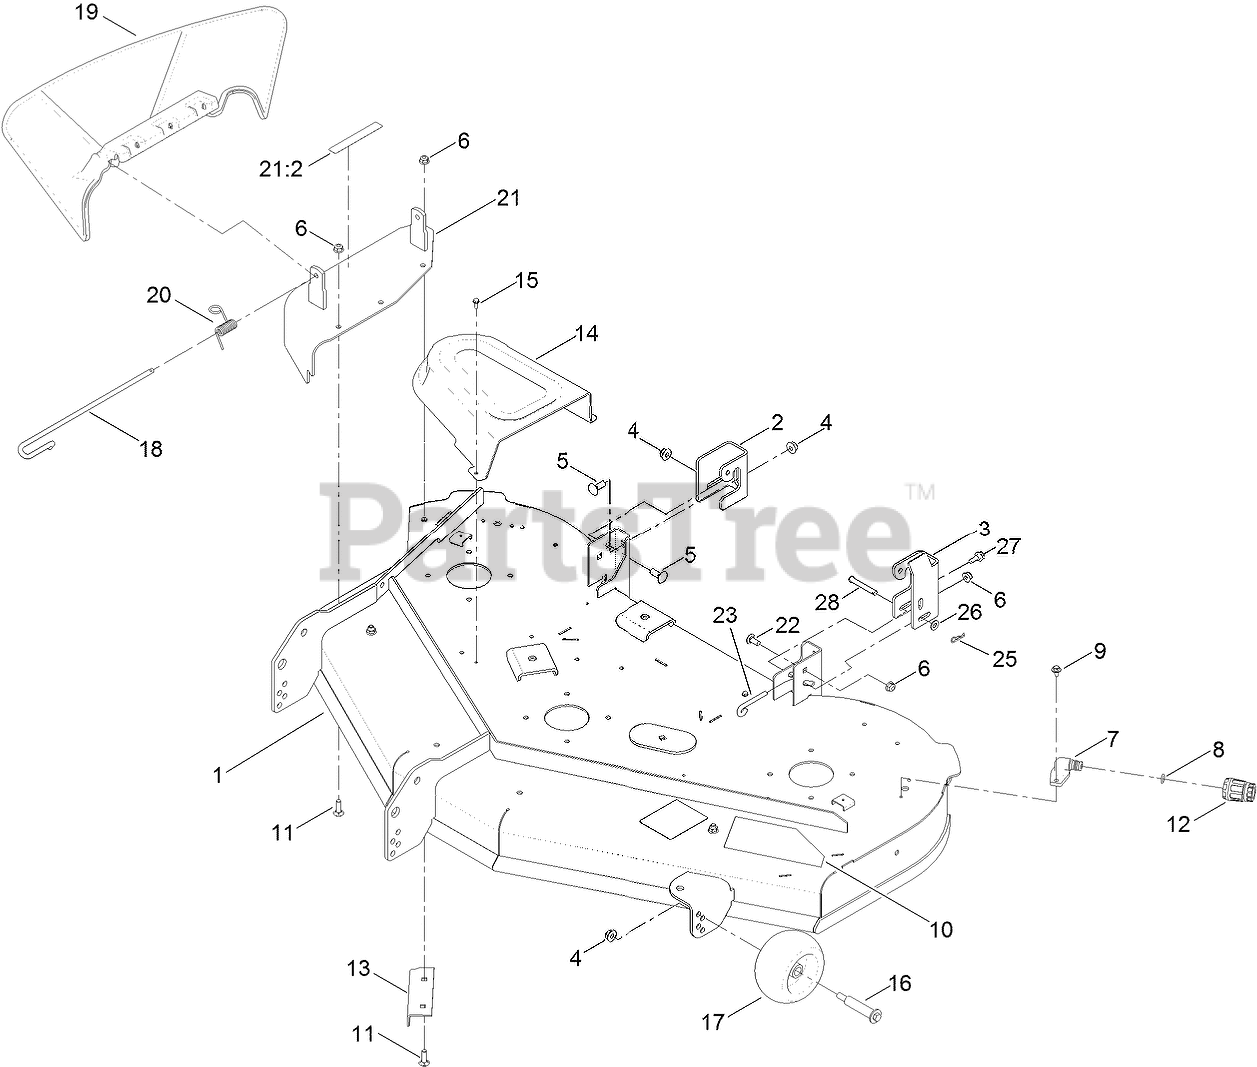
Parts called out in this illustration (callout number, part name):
1	50 INCH DECK AND DECAL ASM
2	BRACKET-HANGER, RH
3	BRACKET-HANGER, LH
4	NUT-HF, NI
5	BOLT-CARR
6	NUT-HF, NI
7	FITTING-WASHOUT
8	O-RING
9	SCREW-HHFTF
10	DECAL-DECK
11	SCREW-CARR
12	CONNECTOR-HOSE
13	BAFFLE-CUTOFF
14	COVER-BELT
15	SCREW-TAPTITE
16	BOLT-SHOULDER
17	ROLLER-SCALP, ANTI
18	PIN-CHUTE
19	DEFLECTOR-DISCHARGE
20	SPRING-TORSION
21	COVER ASM W/DECAL
21:2	DECAL-DANGER
22	SCREW-CARR
23	ROD-LEVEL, DECK
25	PIN-COTTER
26	WASHER-PLAIN
27	SCREW-SHOULDER, HHF
28	PIN-CLEVIS
